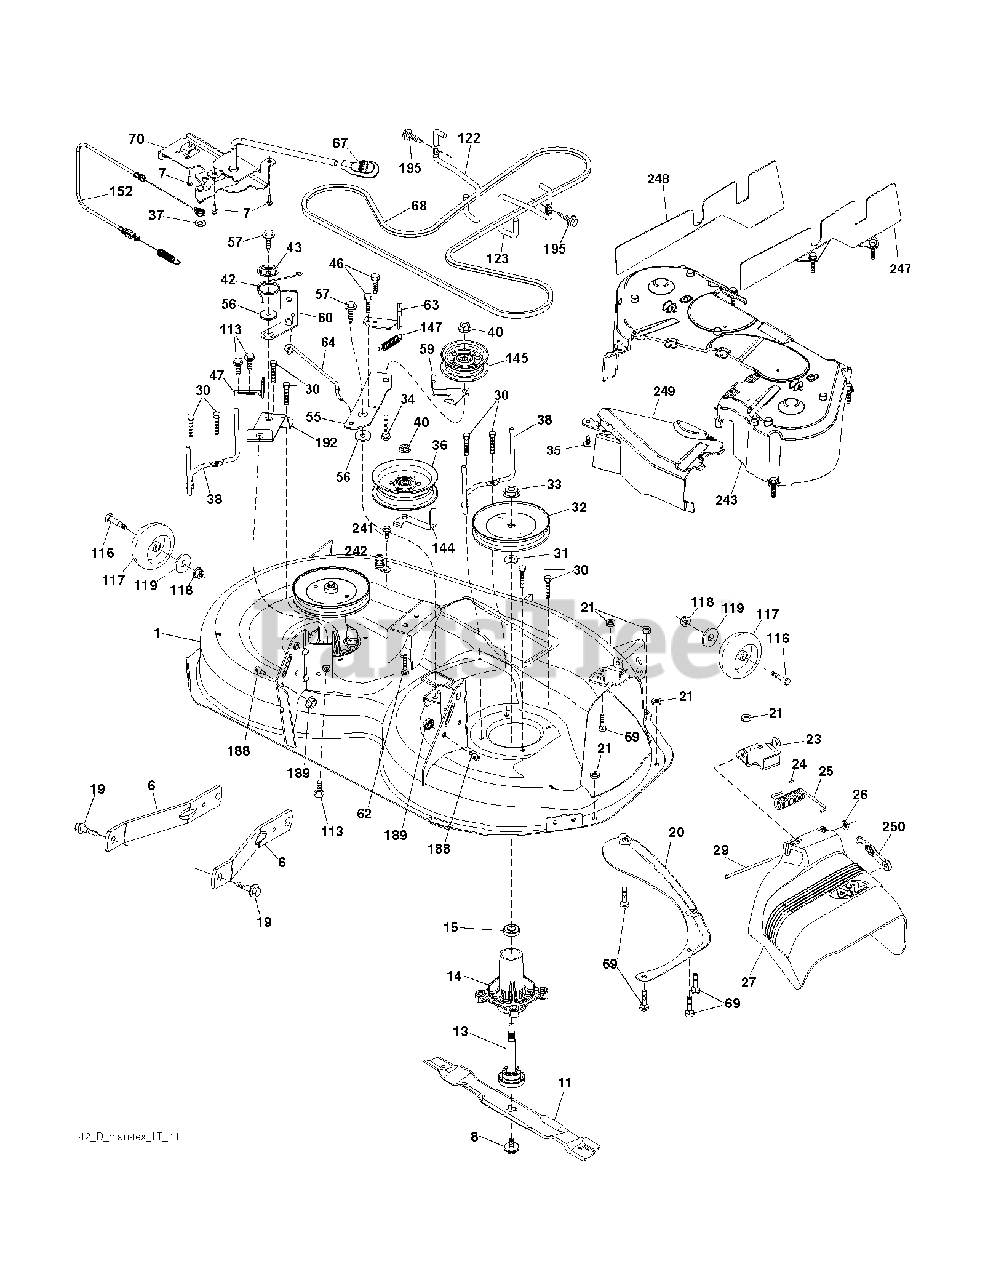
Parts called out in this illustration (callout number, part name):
1	DECK.WELDMENT.42"
6	ARM.SUSPENSION.MOWER.R
7	SCREW.#10 X 0.750.BOS THREAD
8	BOLT.WASHER.ASM.7/16-2
11	42" HI-LIFT BLADE
13	SHAFT.ASM.MDRL.N/GREASE.38
14	HOUSING MANDREL
19	BOLT.SHOULDER
20	BAFFLE.VORTEX
21	LOCKNUT
23	BRKT.DEFLECTOR.38"2005+
24	CAP-SLEEVE LT
25	SPRING.TORSION.DEFLECT
26	NUT PUSH M
29	ROD.HINGE
30	SCREW, WASHER HEAD
31	WASHER.SPACER.MANDREL
32	PULLEY.MANDREL.5.438.PD
33	NUT.FLANGE.LOCK.TOP
34	BOLT.3/8-16X1.50
35	FASTENER.XMAS.TREE
36	PULLEY.IDLER.2006
38	KEEPER.BELT.LH.MANDREL
40	NUT LOCK FLG 3/8-16 UNC
42	SPRING.TORSION.BRAKE
43	SRPING.TORSION.RETAINE
46	SCREW.1/4-20X5/8
47	BRKT.CLUTCH.CABLE
55	IDLER.ARM.42"
56	SPACER.RETAINER
57	SCREW 3/8-16X1
59	GUARD, BELT
60	ARM BRAKE MOWER
62	BOLT
63	ARM BRAKE MOWER
64	LINK BRAKE
67	HANDLE.CLUTCH.CABLE.LT
68	BELT.DECK.DRIVE.42"
69	BOLT
70	CLUTCH.ASM.MANUAL.LT.TEX
113	BOLT.5/16HEX.WHS.HD
117	WHEEL.GAGE.HALF.SPOKED
118	NUT LOCK FLG 3/8-16 UNC
119	WASHER
122	KEEPER BELT ENGINE LH
123	KEEPER BELT RH
144	KEEPER.BELT.MOWER
145	PULLEY.IDLER.48"PRIMARY
147	RETURN SPRING
152	CLUTCH CABLE
188	STUD.FASTNER.W/ANTI-ROTATE
189	NUT LOCK HEX FLANGE 5/16-18
192	BRKT.BRAKE.STAND.LH.
195	SCREW, 3/8-16X3/4
242	PORT.WASHOUT
